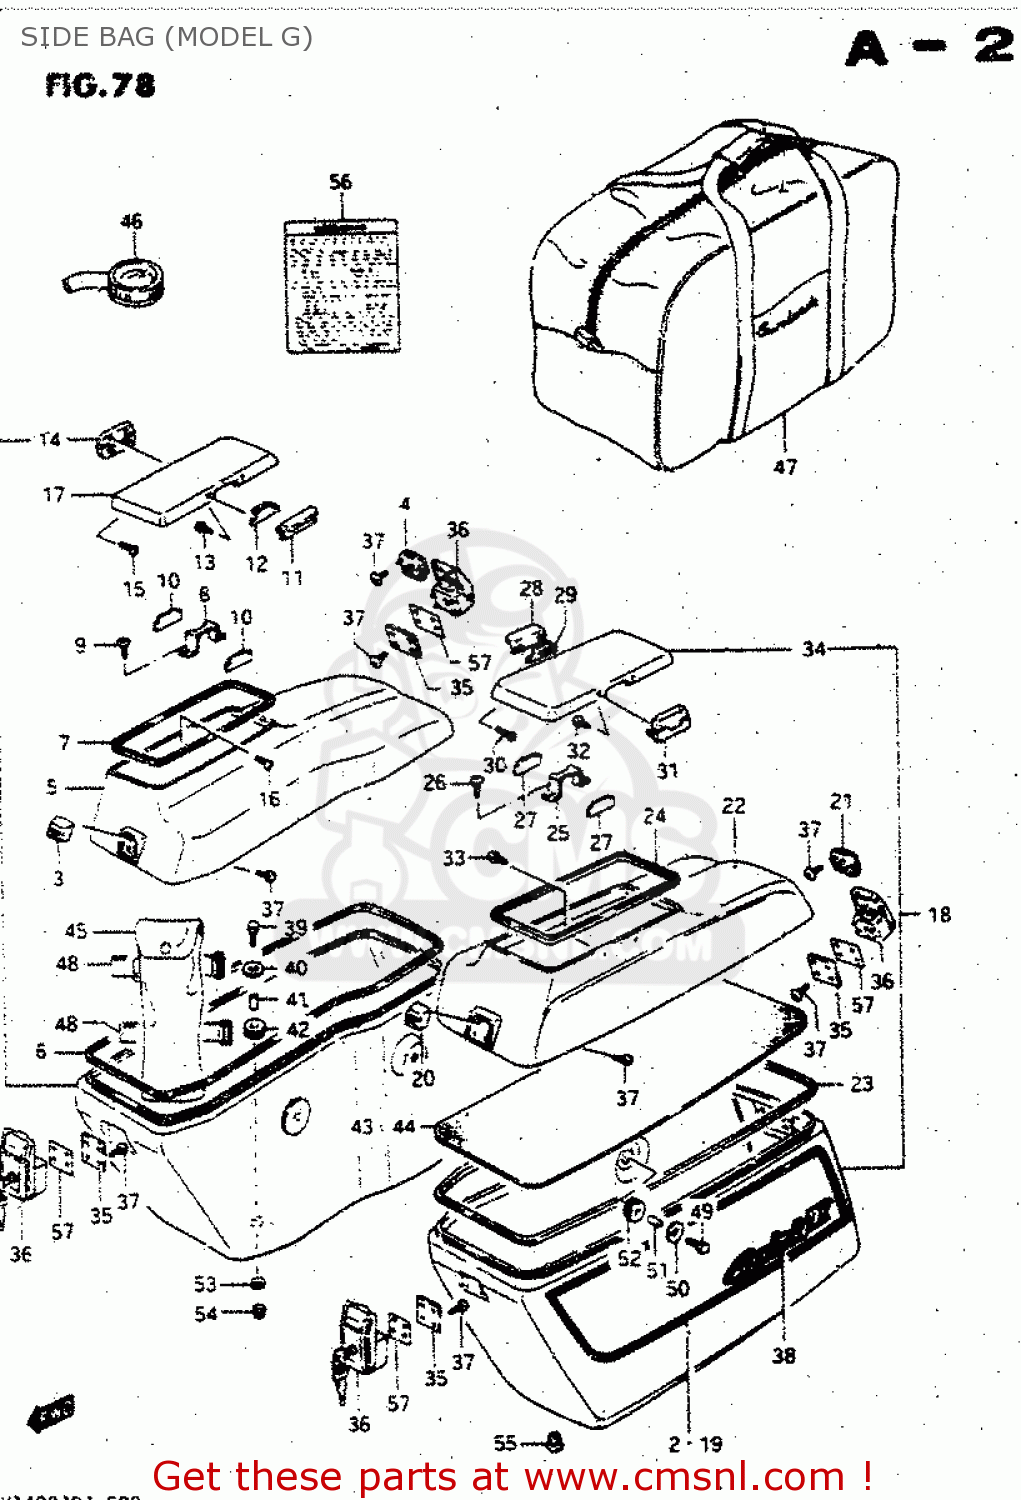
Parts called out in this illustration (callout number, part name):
1	SIDE BAG ASSEMBLY,RIGHT
2	TAPE SET,SIDE BAG,RIGHT
3	PLATE,TRUNK LID LOCK
4	PLATE,SIDE BAG LID LOCK
5	LID,SIDE BAG,RIGHT
6	SEAL,SIDE BAG
7	SEAL,SIDE BAG
8	HOLDER,LID LOCK MAGNET
9	SCREW
10	PLATE,LID LOCK
11	LEVER,SIDE POCKET OPEN
12	PLATE,LID LOCK NO.1
13	SCREW
14	HINGE,LID SIDE BAG POCKET
15	SCREW
16	SCREW
17	LID, POCKET
18	SIDE BAG ASSEMBLY,LEFT
19	TAPE SET, SIDE BAG LH
20	PLATE,TRUNK LID LOCK
21	PLATE,SIDE BAG LID LOCK
22	LID,SIDE BAG,LEFT
23	SEAL,SIDE BAG
24	SEAL,SIDE BAG
25	HOLDER,LID LOCK MAGNET
26	SCREW
27	PLATE,LID LOCK
28	LEVER,SIDE POCKET OPEN
29	PLATE,LID LOCK NO.1
30	SCREW
31	HINGE,LID SIDE BAG POCKET
32	SCREW
33	SCREW
34	LID, POCKET
35	SET PLATE,LOCK SIDE BA
36	LOCK ASSY, SIDE BAG
37	SCREW
38	EMBLEM,SIDE BAG,RIGHT
39	BOLT 6X30
40	WASHER (6.5X29X1.6)
41	SPACER(6.3X9.3X16.5)
42	CUSHION
43	SEAT, BOTTOM RH
44	SEAT, BOTTOM LH
45	TOOL ASSY
46	GAUGE ASSY,AIR PRESSURE
47	LUGGAGE BAG,SIDE BAG
48	BAND
49	BOLT
50	WASHER (6.5X29X1.6)
51	SPACER(6.3X9.3X16.5)
52	CUSHION
53	WASHER (6.5X18X2)
54	NUT
55	CAP(OD:12)
56	LABEL (WARNING)
57	PACKING SEAT
